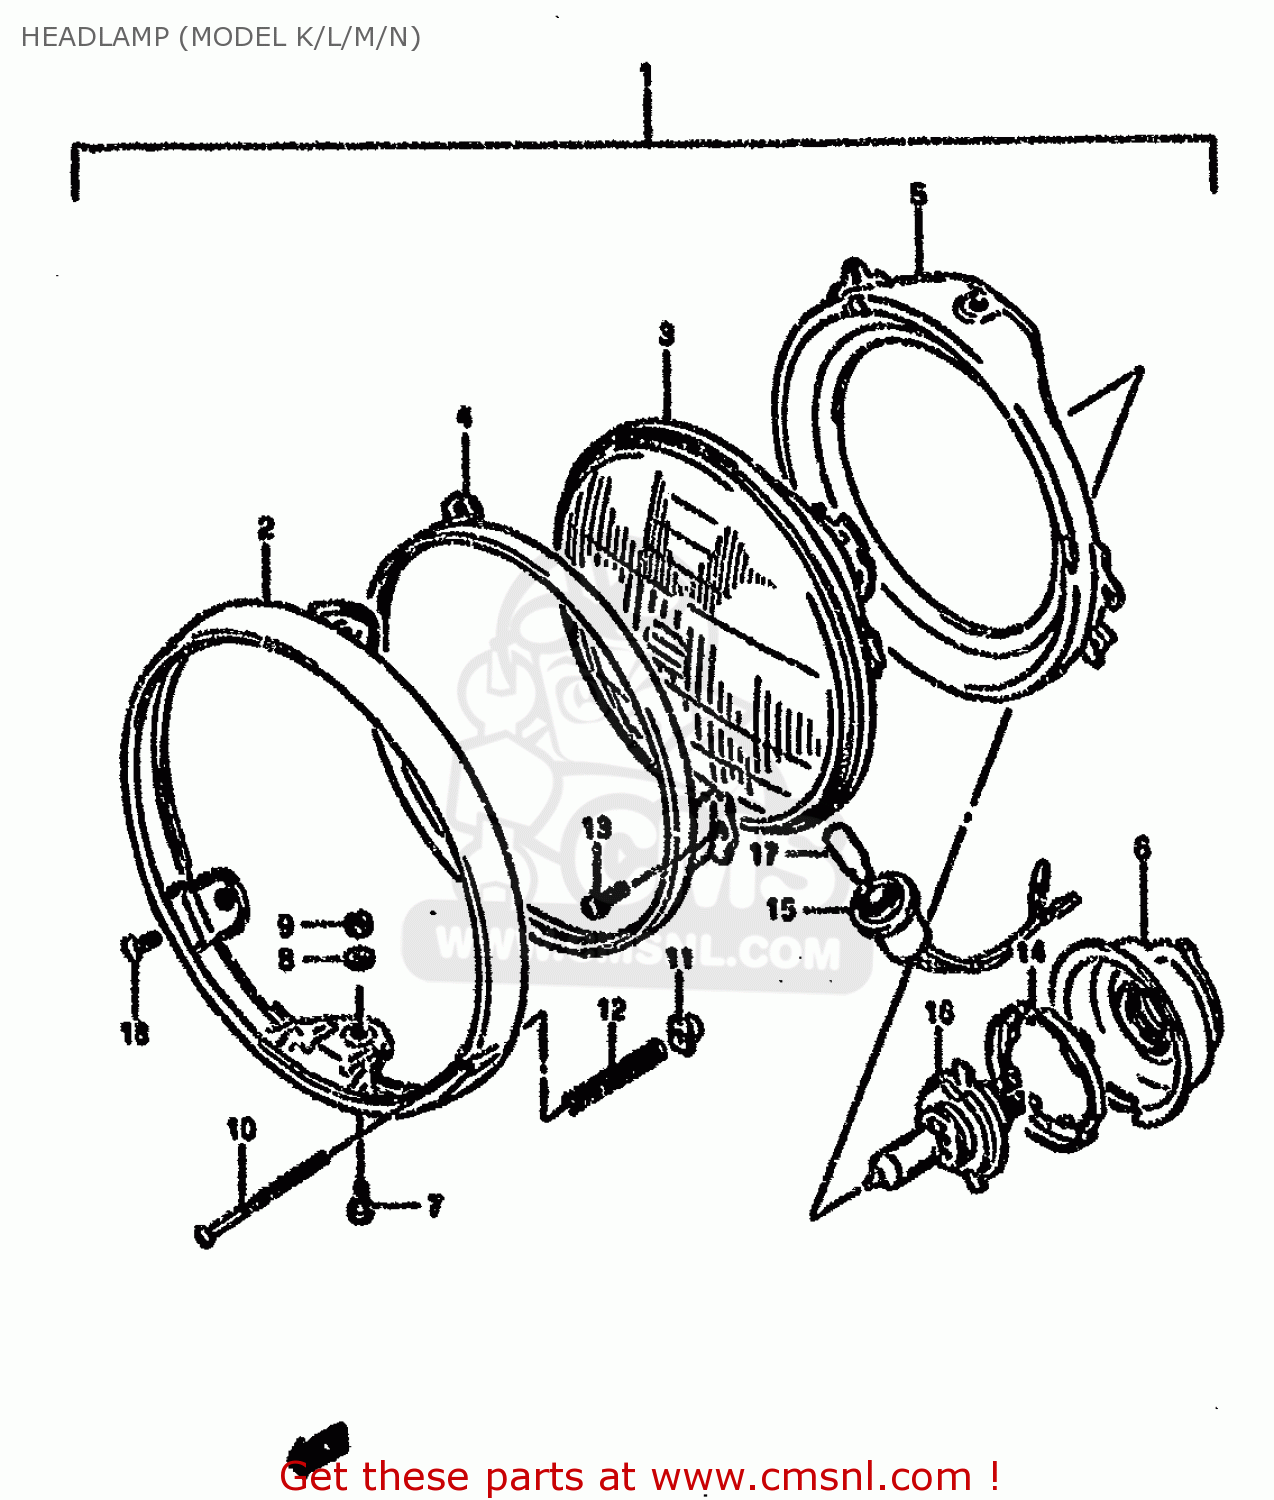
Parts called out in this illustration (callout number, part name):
1	HEADLAMP ASSY
2	RIM,HEADLAMP
3	LAMP UNIT
4	RETAINING RING
5	RING
6	COVER,HEADLAMP SOCKET
7	H/LAMP LENS UNIT FITING SCRE
8	WASHER,LOCK
9	NUT
10	SCREW
11	NUT
12	SPRING,ADJUSTING
13	SCREW
14	SETTING,BULB
15	SOCKET
16	BULB(12V60/55W,H4)
17	BULB(12V4W)
18	SCREW
